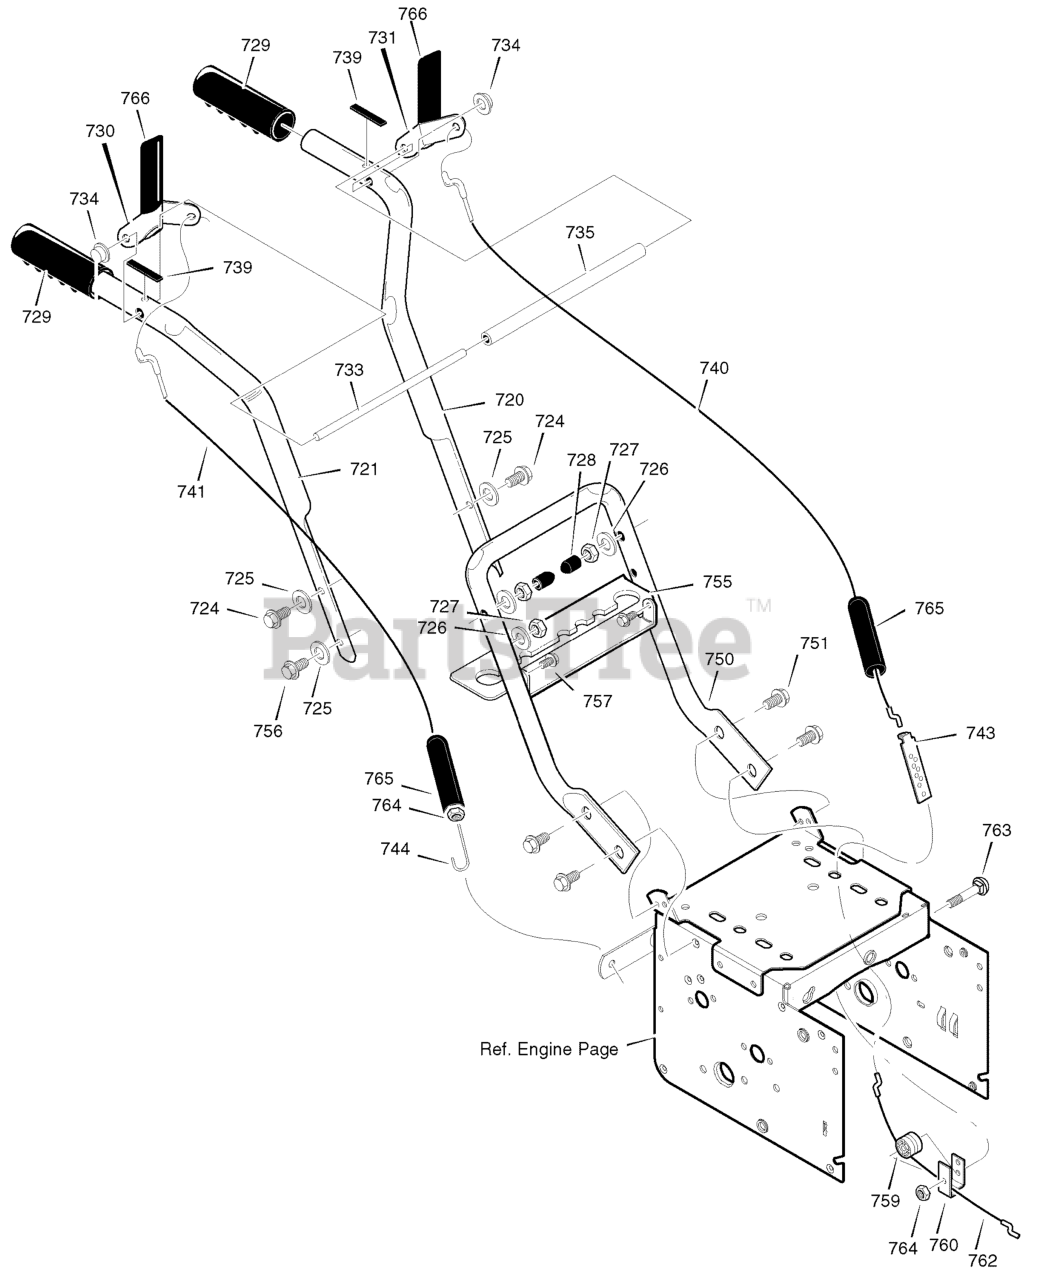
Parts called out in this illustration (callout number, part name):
720	HANDLE, UPPER LH
721	HANDLE, UPPER RH
724	SCREW, 5/16-18 X 2.75
725	WASHER, FLAT
726	WASHER, SPTLK .31X.58X.08
727	NUT, 5/16-18
728	STOP, RED PLASTIC
729	GRIP-HANDLE FINGER
730	LEVER, ASSY CLUTCH DRIVE RH
731	LEVER, ASSY CLUTCH DRIVE LH
733	ROD, PIVOT CLUTCH
734	NUT, PUSH ON CAP
735	SPACER-HANDLE
739	BUMPER, RECTANGLE
740	CABLE, CLUTCH 28.44L
741	CABLE, AUGER CLUTCH
743	BRACKET, CABLE ADJUSTER
744	SPRING, AUGER CLUTCH
750	HANDLE, LOWER
751	SCREW 5/16-18 X .75
755	BRKT, GEAR SELECTOR
756	SCREW, 5/16-18 X 2.00
757	SCREW, 1/4-20 X 0.63
759	SPOOL-CABLE, AUGRT CLUTCH
760	BRACKET, CABLE SPOOL YZ
762	CABLE, LOWER DRIVE 12"
763	BOLT, HEX 1/4-20 X 1.75 YZ
764	NUT, 1/4-20
765	BOOT, CLUTCH SPRING
766	GRIP
